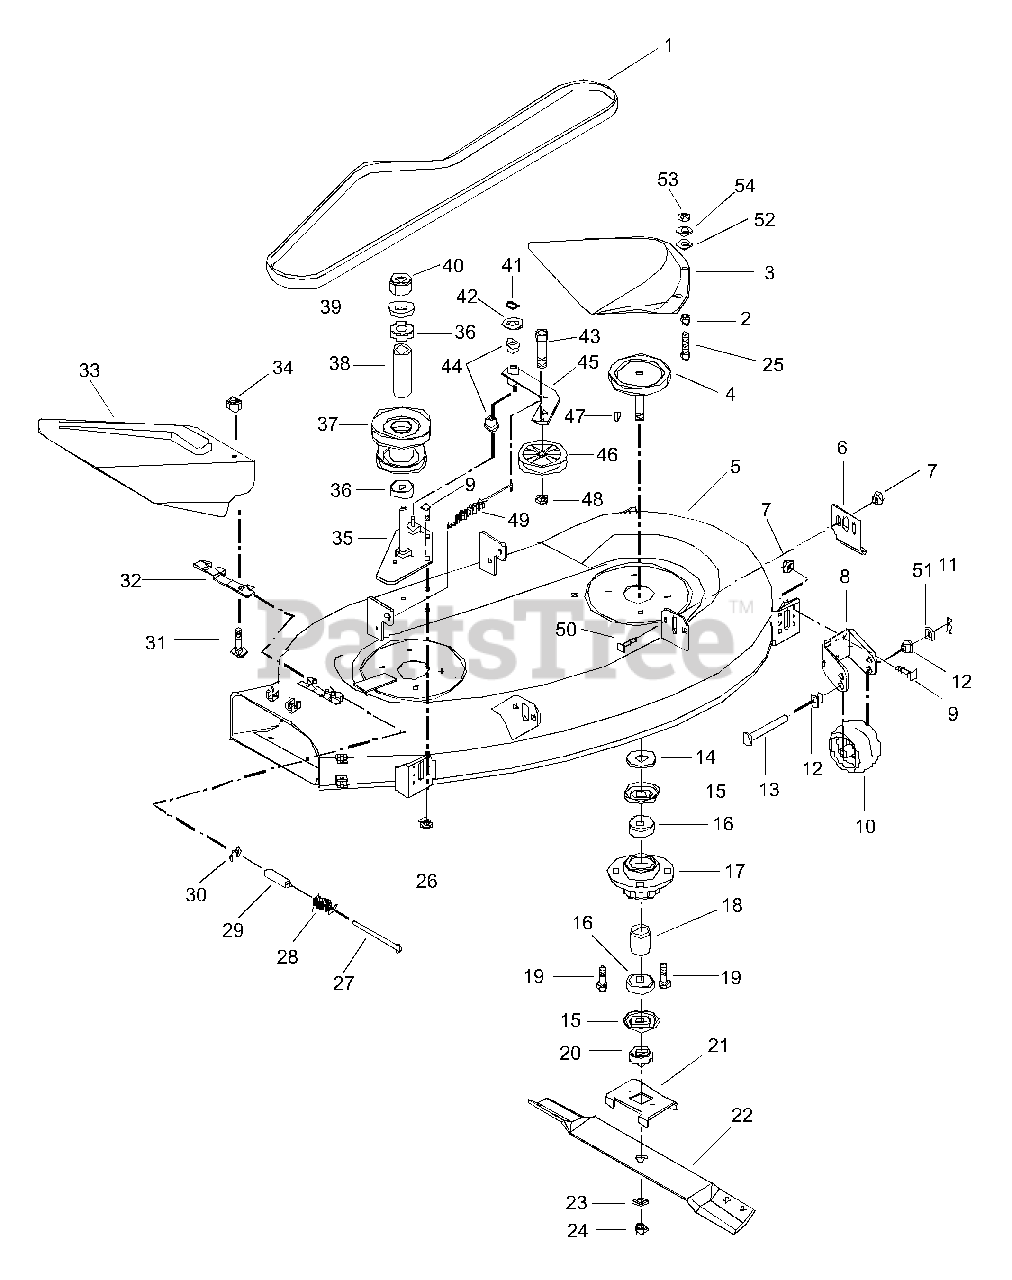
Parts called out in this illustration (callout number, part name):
2	Nut-Locking-Center .375-16
4	Left Spindle Sheave
4	Right Spindle Sheave
5	40" Deck w/Decals
5	40" Deck Complete
6	Mower Adjustment Tab
7	Nut-Locking-Flange .312-18
8	Roller Clevis
9	Bolt-Round Head Square Neck .31-18 x .62
10	Roller
11	Pin-Hair-Internal .08 x .18 x 1.18
12	Bushing-Flange .372 x .500 x .312 x .625
13	Clevis Pin .368/.373 x 3.25
14	Washer-Flat-Steel .755 x 1.250 x .125
15	Bearing Slinger
16	Bearing-Ball .750 x 1.781 x .61
17	Spindle Housing
18	Spacer .751 x 1.000 x 1.140
19	Bolt-Round Head Square Neck .38-16 x 1.0 Grade 5
20	Retainer Hub
21	Blade Tray 48
23	Washer-Lock .750 x .188
24	Nut-Jam .75-10
25	Bolt-Hex .38-16 x 1.00 Grade 5
26	Nut-Locking-Flange .312-18
28	Spring-Torsion .095 x .50 x 1.0
29	Bushing
30	Ring-Retaining-External .313 x .025
31	Bolt-Round Head Square Neck .25-20 x .50
32	Hinge Plate
33	40" Deflector
34	Nut-Locking-Flange .250-20
35	Mount Plate 40"
36	Bearing-Ball .625 x 1.375 x .44
37	Jackshaft Pulley
38	Spacer .640 x .880 x 2.768
39	Washer-Flat-Steel .630 x 1.005 x .062
40	Nut-Locking-Nylon .625-18
41	Ring-Retaining-External .500 x .042
42	Washer-Flat-Steel .505 x .880 x .072
43	Bolt-Hex .38-16 x 1.50 Grade 5
44	Bushing-Flange .500 x .625 x .312 x .750
45	Idler Arm
46	Idler-Flat 3.00 x .38
47	Key-Woodruff .188 x .625 x .31
48	Nut-Locking-Center .375-16
49	Spring-Tension .113 x .812 x 7.000
50	Bolt-Round Head Square Neck .31-18 x .75 Grade 5
51	Washer-Plastic .390 x .875 x .062
52	Washer-Flat-Steel .406 x .812 x .065
53	Nut-Hex .38-16
54	Washer-Locking .38 x .094
